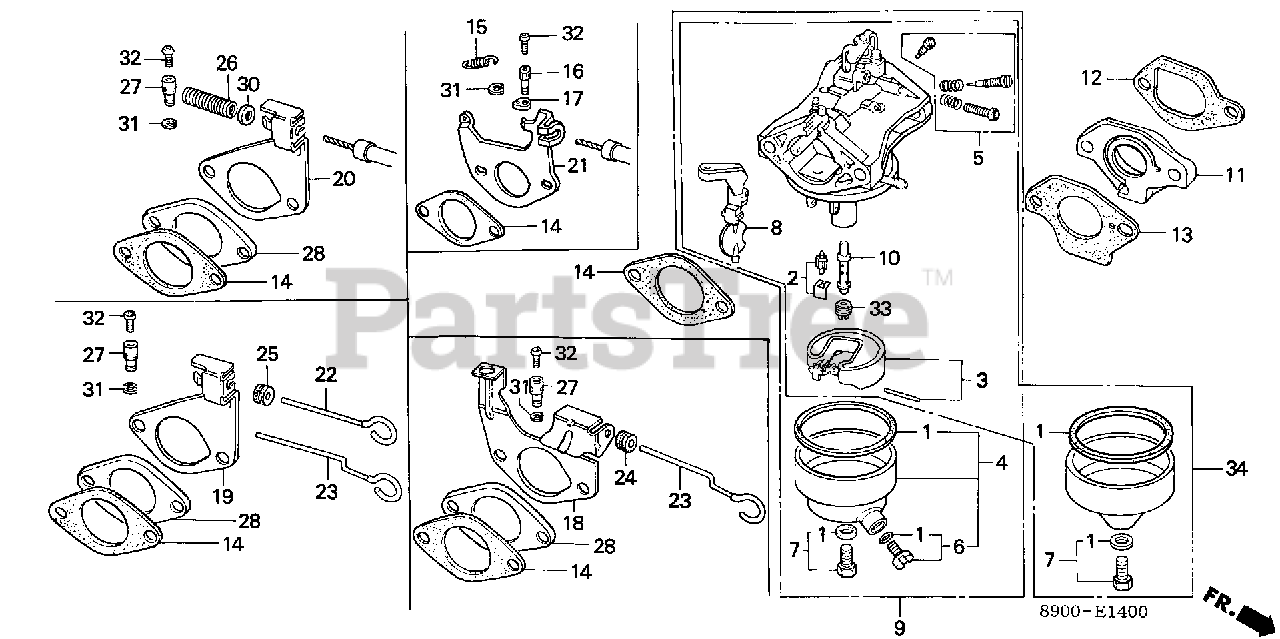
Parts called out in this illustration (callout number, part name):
1	GASKET SET
2	VALVE SET, FLOAT
2	VALVE SET, FLOAT (CARBURETOR NO.)
3	FLOAT SET (CARBURETOR NO.)
4	CHAMBER SET, FLOAT (CARBURETOR NO.) (NOT AVAILABLE)
5	SCREW SET A (CARBURETOR NO.)
5	SCREW SET A (CARBURETOR NO.) (NOT AVAILABLE)
7	SCREW SET (CARBURETOR NO.)
7	SCREW SET
8	CHOKE SET (CARBURETOR NO.)
10	NOZZLE, MAIN (CARBURETOR NO.)
10	NOZZLE, MAIN (CARBURETOR NO.) (NOT AVAILABLE)
11	INSULATOR, CARBURETOR
12	GASKET, INSULATOR
13	GASKET, CARBURETOR
14	GASKET, AIR CLEANER
19	STAY, CHOKE CONTROL (NOT AVAILABLE)
22	ROD, CHOKE CONTROL (NOT AVAILABLE)
25	GROMMET, CHOKE ROD
27	HOLDER, CABLE
28	SPACER, AIR CLEANER (NOT AVAILABLE)
31	CIRCLIP (5MM)
32	SCREW, PAN (4X8)
33	JET, MAIN (#88) (CARBURETOR NO.)
33	JET, MAIN (#90) (CARBURETOR NO.)
33	JET, MAIN (#92) (CARBURETOR NO.)
33	JET, MAIN (#95) (CARBURETOR NO.)
33	JET, MAIN (#98) (CARBURETOR NO.)
33	JET, MAIN (#100) (CARBURETOR NO.)
33	JET, MAIN (#102) (CARBURETOR NO.)
34	CARBURETOR ASSY. (BB35A A) (NOT AVAILABLE)
34	CARBURETOR ASSY. (BB35A B) (NOT AVAILABLE)
34	CARBURETOR ASSY. (BB35C G)
